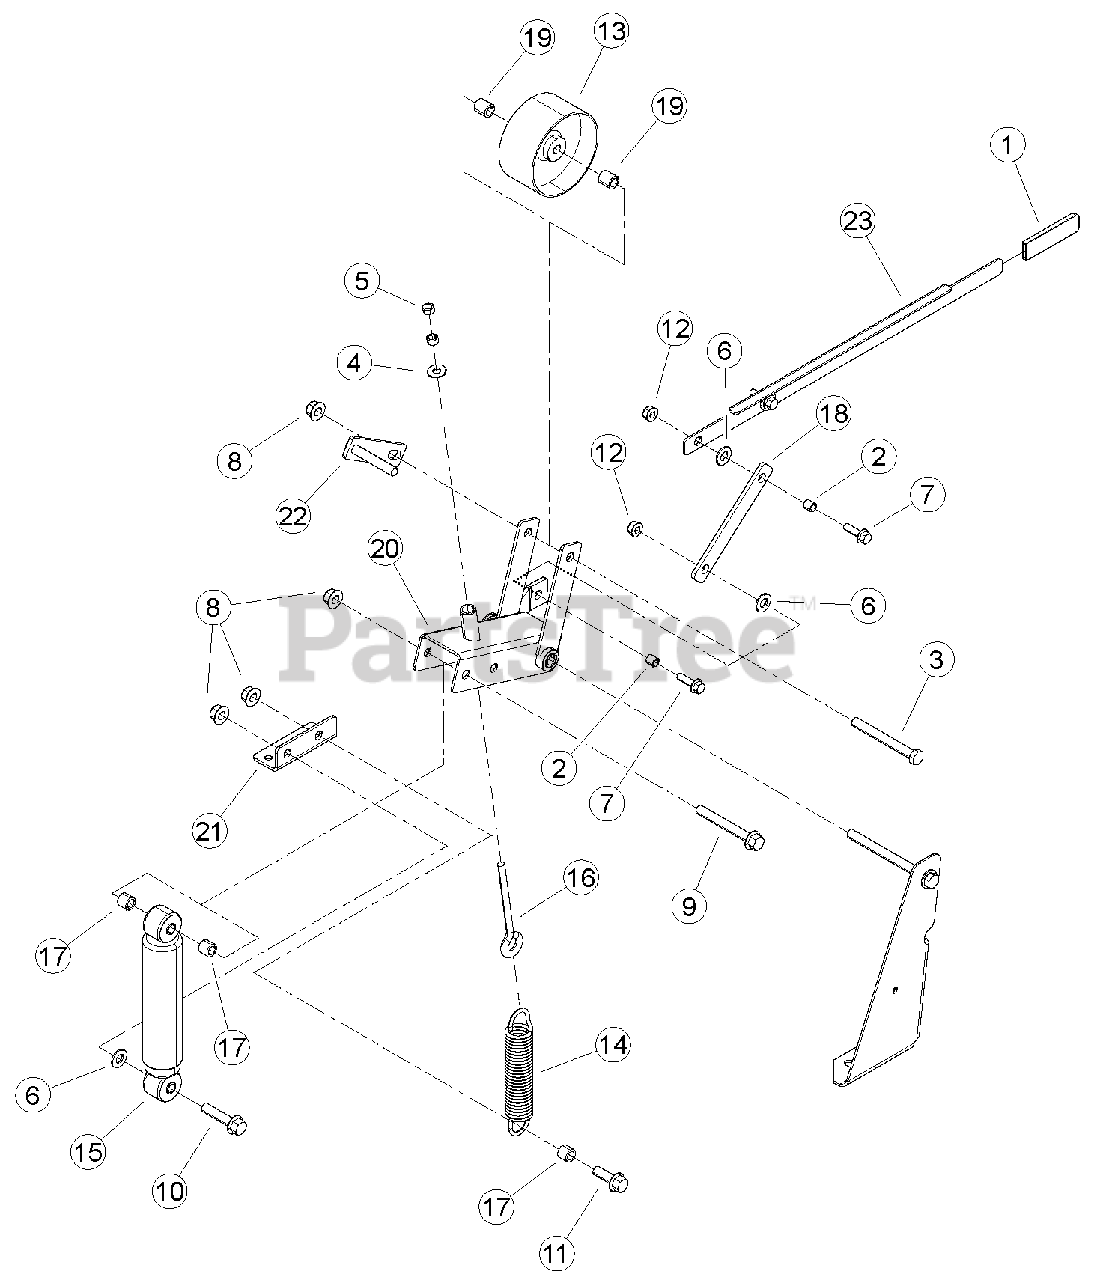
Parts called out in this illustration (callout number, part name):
1	GRIP, CLUTCH HANDLE
2	BUSHING, 3/8 X 1/2 SLEEVE LUBE
3	BOLT, 1/2 X 4-1/2" GR5 HHCS NC ZP
4	WASHER, 3/8" FLAT ZP
5	NUT, 3/8" HEX NC ZP
6	WASHER, 1/2" SAE FLAT ZP
7	BOLT, 3/8 X 1-1/4 FLANGE NC
8	NUT, 1/2-13 NYLOCK FLANGE
9	BOLT, 1/2-13 X 4 HWH GR5 CZP
10	BOLT, 1/2 -13 X 2-1/4 FLANGE NC
11	BOLT, 1/2-13 X 1-1/2 GR5 FLANGE NC
12	NUT, 3/8-16 NYLOCK FLANGE
13	PULLEY, IDLER 5 X 2.50"
14	SPRING, 7-3/4" EXTENSION
15	ABSORBER, IDLER SHOCK
16	EYEBOLT, 3/8 X 5" LG 4-1/4THD ZP
17	SPACER, 0.75 X 0.620
18	LINK, ENGAGEMENT ARM
19	SPACER, IDLER SHEAVE
20	WELDMENT, IDLER ARM
21	BRACKET, SPRING ANCHOR
22	WELDMENT, BELT PIN
23	LEVER, CLUTCH ENGAGEMENT
